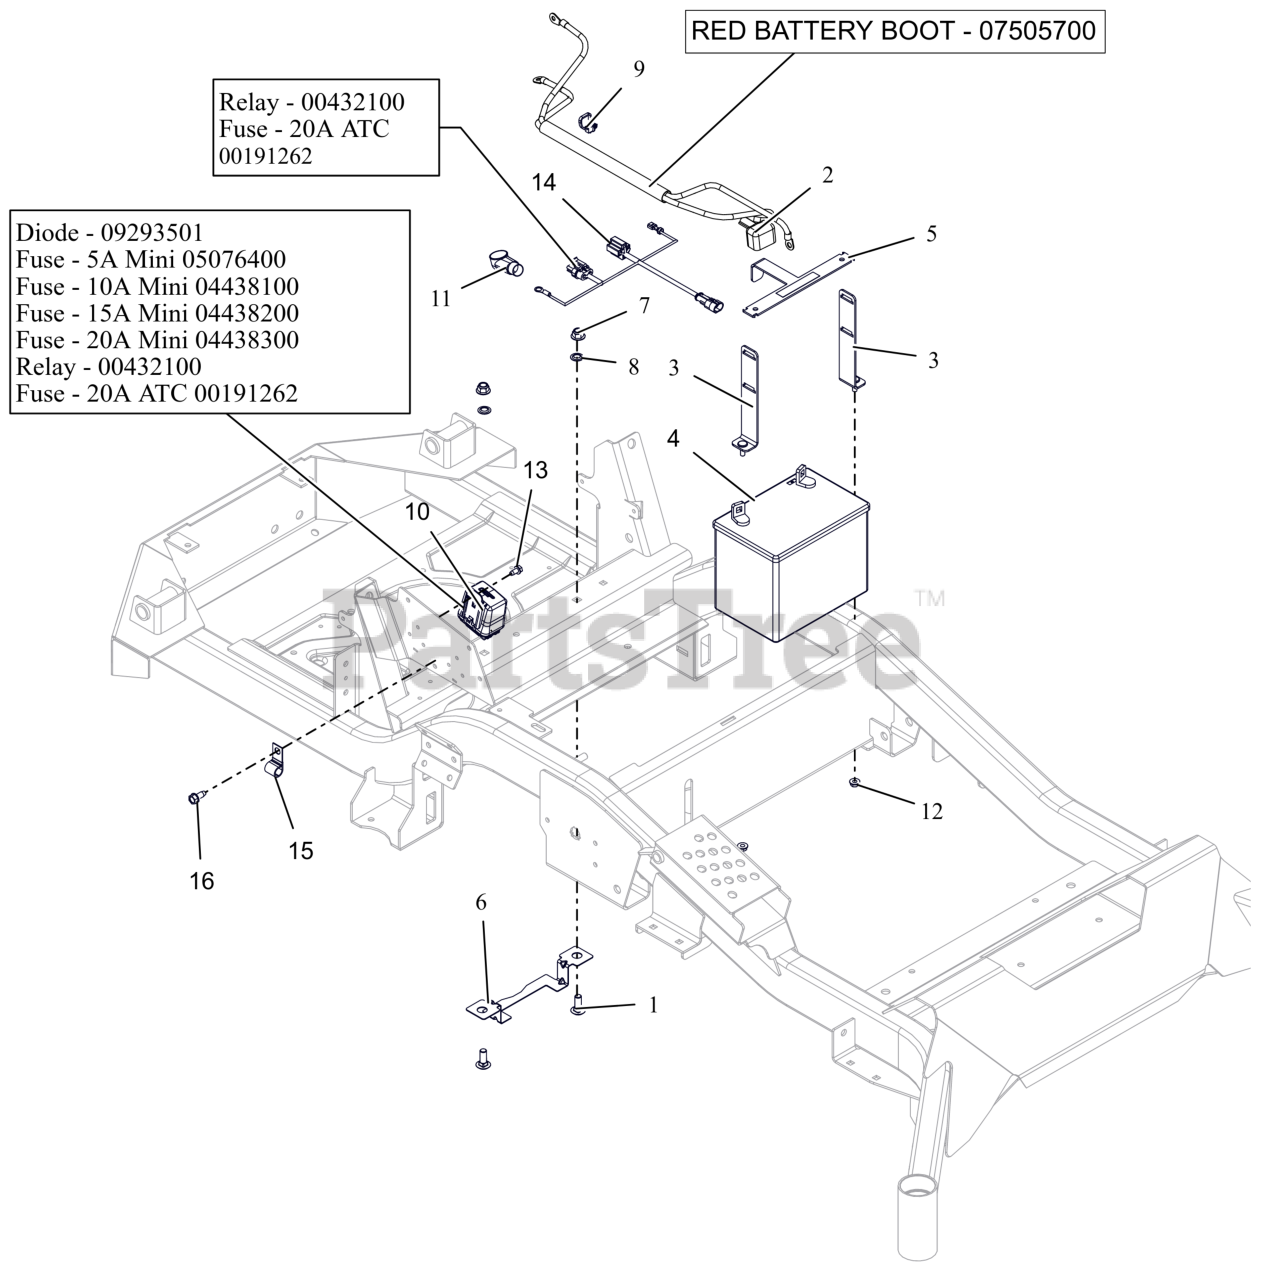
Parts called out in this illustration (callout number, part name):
1	BLT, RHSN .38-16X1.00 G5 ZCC
2	HARNESS, BATTERY HD
2	INSULATOR
3	WMT,BATTERY MOUNT HOLD DOWN
4	BATTERY, 300 CCA 10U1L
5	BRKT, BATTERY TIE DOWN
6	GUARD, ELECTRICAL HARNESS
7	NUT,NYL-FLG .38-16 GF ZCC
8	NUT-PUSH .38 DIA. PAL ZINC
9	CABLE TIE W/ TREE (.25 HOLE)
10	HARNESS, WIRE
10	DIODE, CONNECTOR SHELL
10	RELAY,MICRO5 TERML W/RESISTOR
10	FUSE, 20 AMP BLADE S/O
10	FUSE, 5 AMP MINI-ATC
10	FUSE,10 AMP MINI-ATC
10	Fuse, 15 AMP MINI-ATC
10	FUSE,20 AMP MINI ATC
11	BOOT, .65ID POS
12	NUT-LK-TOP-FLG .250-20 GF ZCC
13	SCR-TAP .25-20X.50 HWH ZCC
14	HARNESS, STARTER ADAPTOR
14	RELAY,SEALED W/DIODE
14	FUSE, 20 AMP BLADE S/O
15	J-CLAMP
16	SCR,TAP .312-18X.75 HWH TR ZCC
